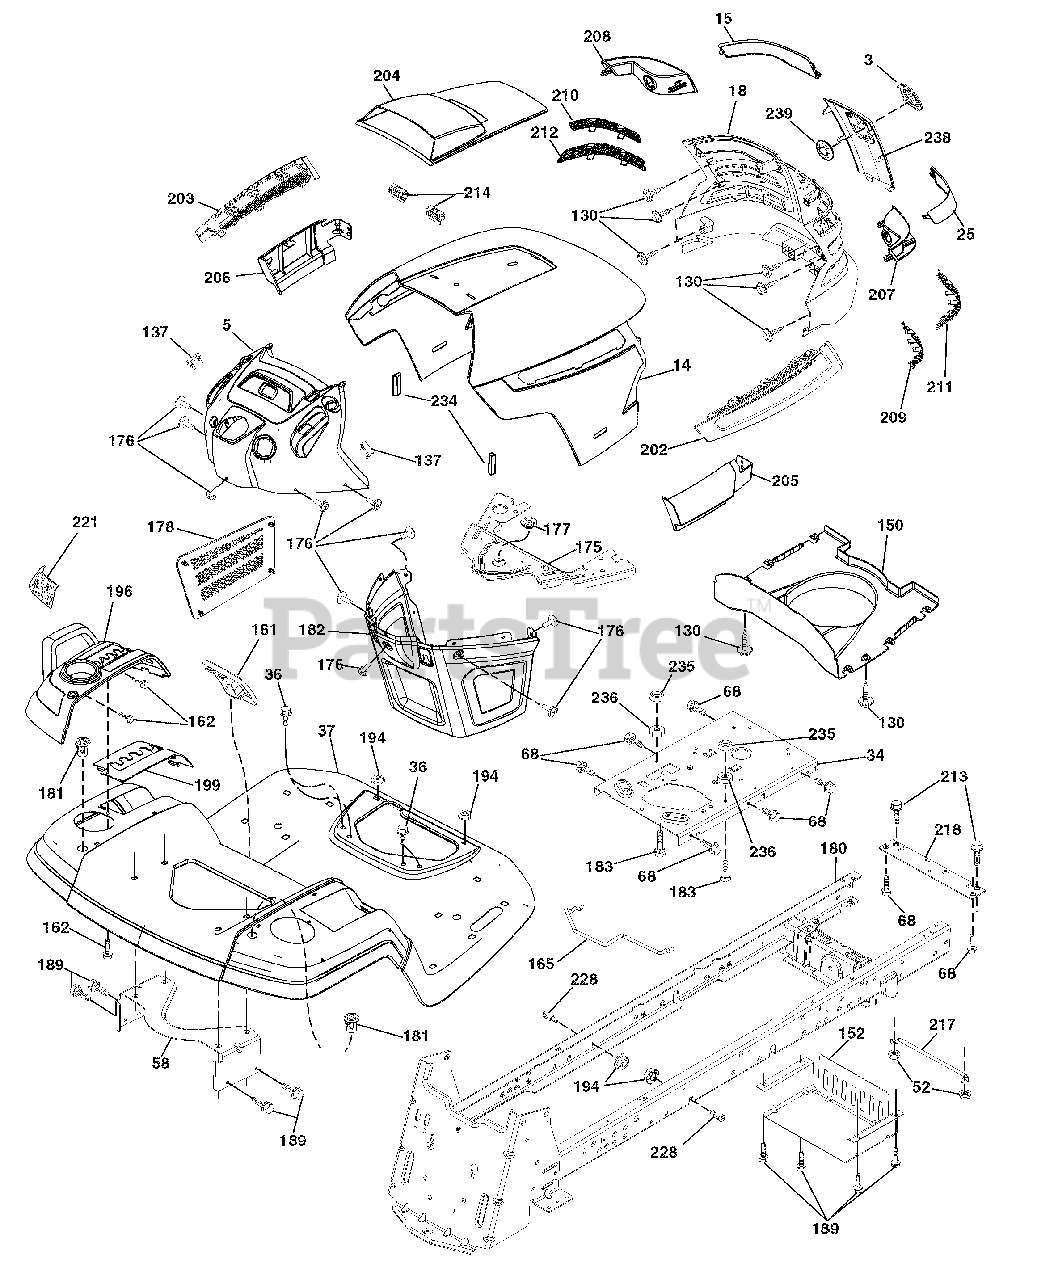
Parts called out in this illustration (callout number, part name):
3	Logo
14	Hood
34	Plate Engine
36	Screw 5/16 - 18 x 3/4
37	Fender
52	Nut Crown Lock 5/16-18
58	Bracket Fender
68	Screw 5/16-18 x 1/2
130	Screw #10 x 0.750 BOS Thread
137	Bumper Dash
150	Duct Heat Hood
152	Shield Browning/Debris
161	Console Fuel Window
162	Screw Hex Wsh Hi-Lo 1/4 x 1/2
165	Bracket Support Tank
175	Crossmember
176	Screw 10-24 x 5/8 Wshd Qdrx
177	Bushing Steering
178	Cargo Asm. Net
180	Chassis
181	Bushing MMT Fender
182	Dash Lower
183	Bolt 5/16-18 unc x 1-1/4
189	Screw 5/16-18 x 3/4
194	Nut Lock 5/16-18
196	Console Asm. Deck Lift
199	Plate Deck Lift
202	Vent Side Hood RH
203	Vent Side Hood LH
204	Vent Asm Hood Top
205	Skirt Hood Side RH
206	Skirt Hood Side LH
209	Insert Hex Top RH
210	Insert Hex Top LH
211	Insert Hex Bottom RH
212	Insert Hex Bottom LH
213	Bolt Hex Hd 5/16-18 unc x 3/4
214	Clip Retainer
218	Hood Stop X Piece
221	Reflector LH
228	Stud Fastener
234	Bumper Hood
235	Spacer Fender
236	Nut Center Lock 5/16-18 unc
